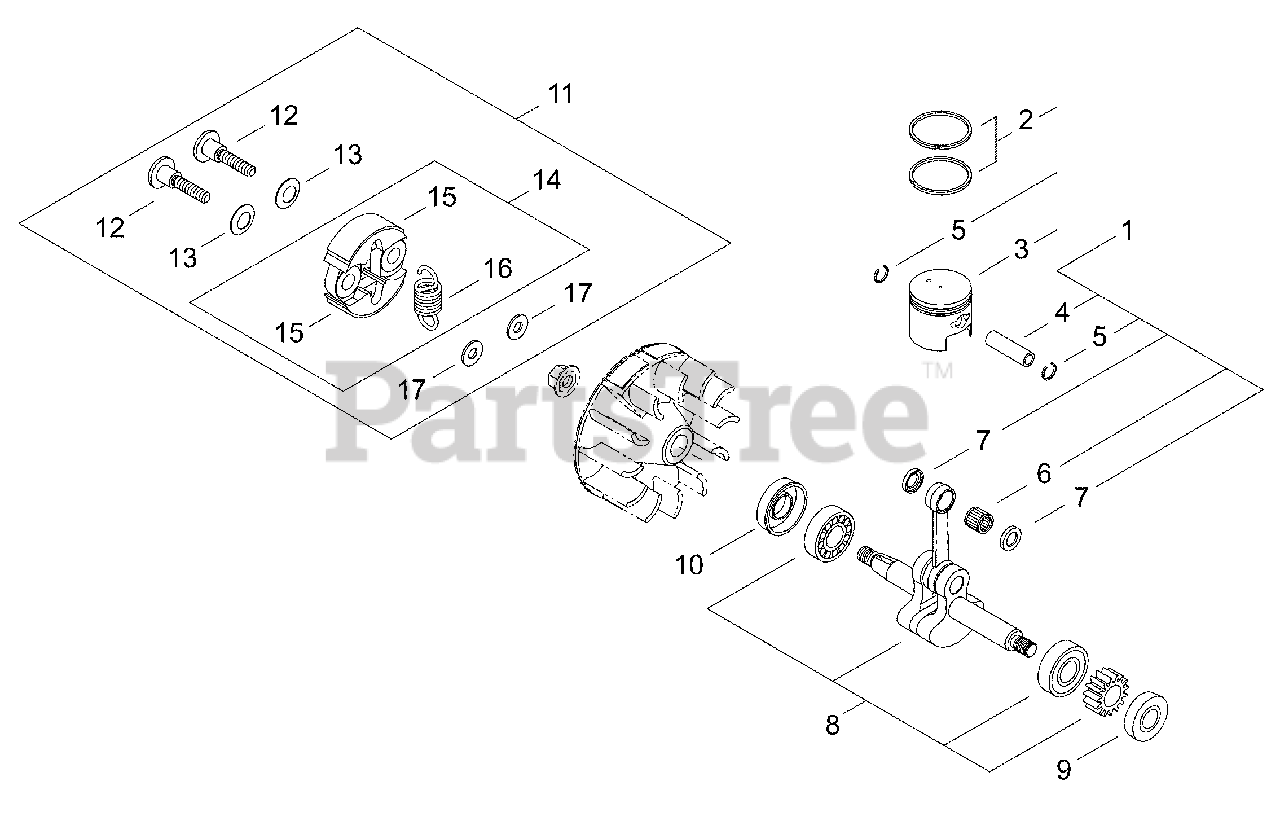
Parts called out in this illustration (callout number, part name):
1	PISTON KIT
2	RING, PISTON
3	PISTON
4	PIN, PISTON
5	RING, SNAP
6	BEARING, NEEDLE 9
7	WASHER, THRUST 9
8	CRANKSHAFT ASSY
9	SEAL, OIL 12
10	SEAL, OIL 12
11	CLUTCH ASSY
12	BOLT, CLUTCH
13	WASHER, SPRING
14	SHOE ASSY, CLUTCH
15	SHOE, CLUTCH
16	SPRING, CLUTCH
17	WASHER 6 MM
